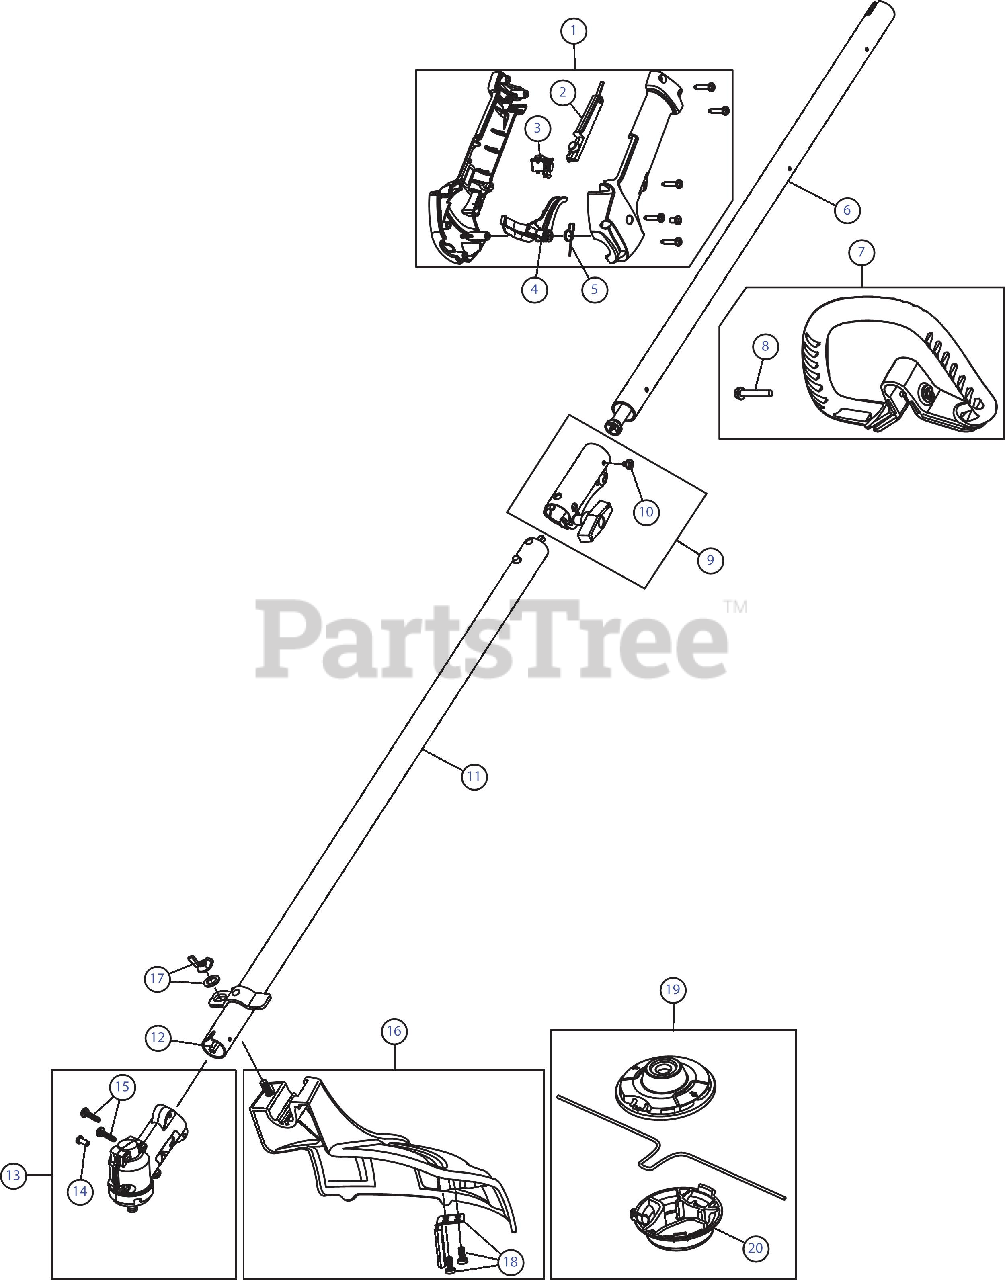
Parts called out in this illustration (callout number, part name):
1	Throttle Housing Assembly (Incl. 2 - 5)
2	Throttle Tigger Lock-Out
3	Throttle Switch Assembly
4	Throttle Trigger
5	Throttle Trigger Spring
6	Upper Shaft Housing Assembly
7	D-Handle (Incl. 8)
8	D-Handle Bolt
9	Split Boom Coupler (Incl. 10)
10	Coupler Anti-Rotation Screw
11	Lower Shaft Housing Assembly
12	Lower Flexible Drive Shaft
13	Gearbox Assembly (Incl. 14 & 15)
14	Gearbox Anti-Rotation Screw
15	Gearbox Mounting Hardware
16	Shield Assembly (Incl. 17 & 18)
17	Shield Mounting Hardware
18	Blade Assembly
19	Cutting Head Assembly (Incl. 20)
20	Glide Cap
